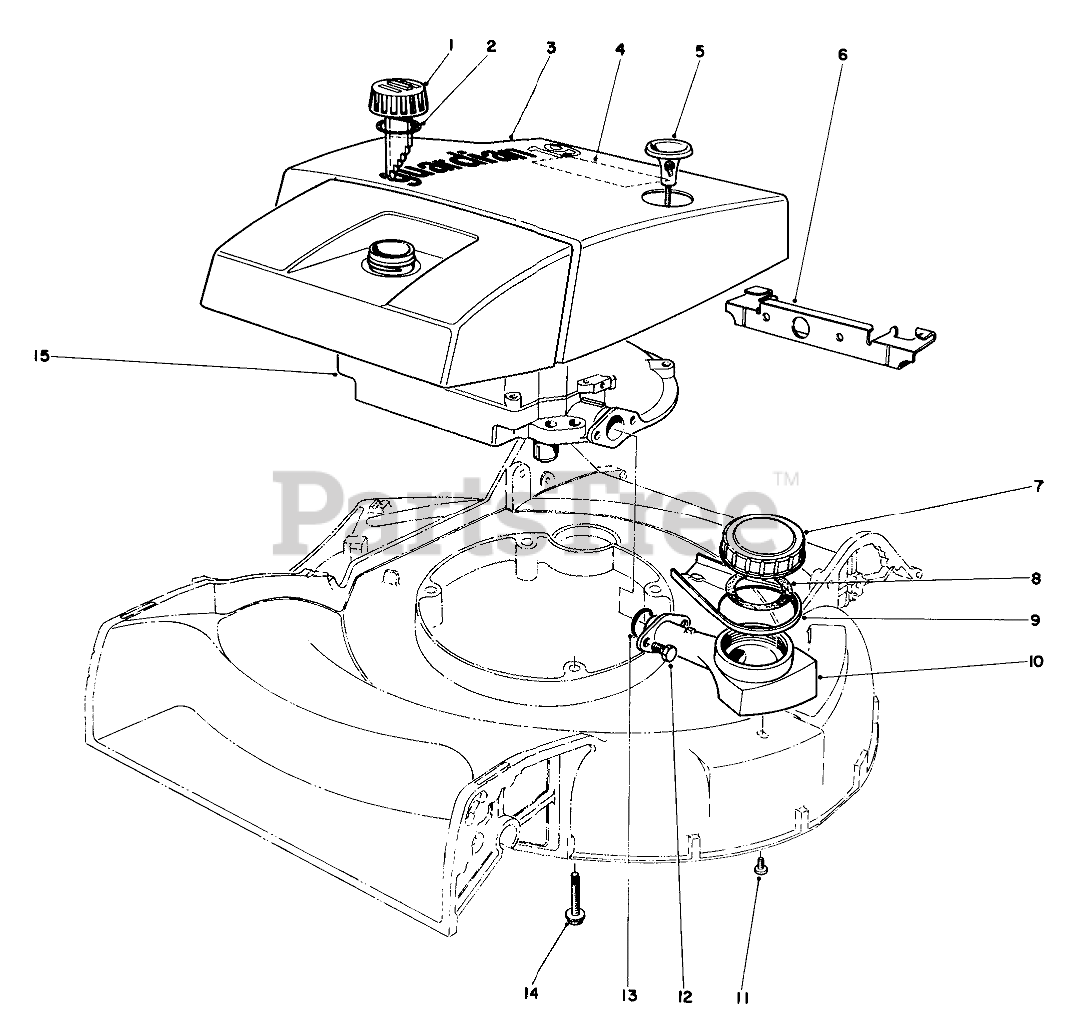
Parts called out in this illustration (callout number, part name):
1	Gas Cap (Incl. Ref. #2)
2	Gasket
3	Shroud
4	Decal-Maintenance
5	Rope Handle
6	Shroud Bracket
7	Oil Gauge Cap
8	VISUAL OILER GASKET
9	Spout
10	Oil Gauge
11	Screw
12	SCREW-HH
13	O RING
14	3/8-16 X 2-3/4 CAPSCR
15	Engine
